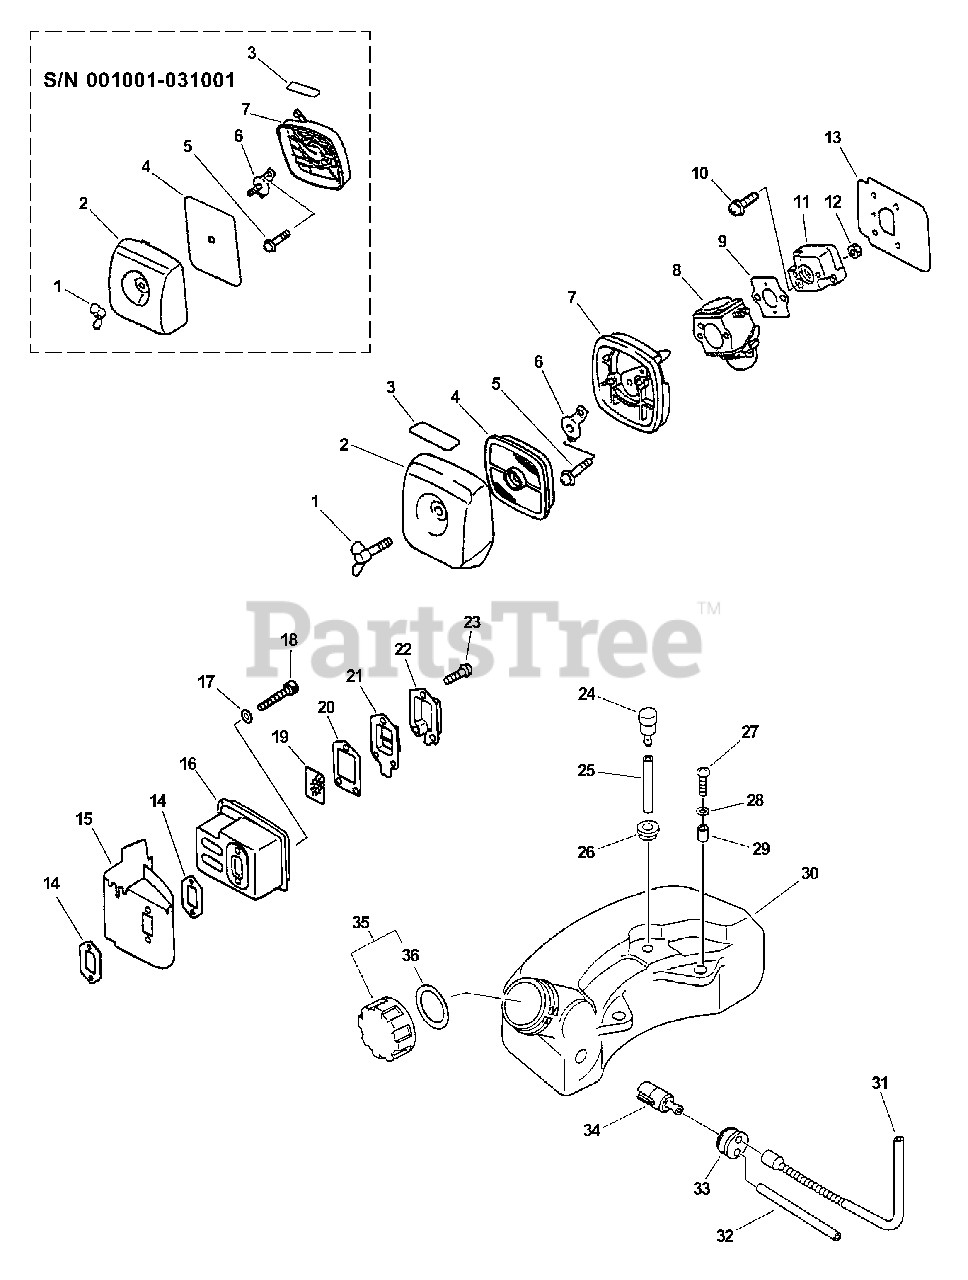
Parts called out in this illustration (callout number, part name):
1	WINGNUT - 6
1	BOLT, WING 5×20
2	COVER, AIR FILTER
3	LABEL, CHOKE
4	FILTER, AIR
4	FILTER, AIR - SINGLE LAYER
5	SCREW 5×65
6	PLATE, PREVENT
7	AIR FILTER CASE ASSY
8	CARBURETOR - C1U-K31A
9	GASKET, INTAKE
10	SCREW 5×20
11	INSULATOR, INTAKE
12	NUT M5
13	HEAT SHIELD, INTAKE
14	GASKET, EXHAUST
15	COVER, EXHAUST
17	WASHER, FLAT 5.5×10×0.8
18	BOLT 5×55
19	SCREEN, SPARK ARRESTER
20	GASKET, EXHAUST
21	GUIDE, EXHAUST
22	GUIDE, EXHAUST - INNER
23	SCREW 4×10
24	VENT ASSY
25	PIPE, FUEL
26	GROMMET
27	SCREW 5×16
28	WASHER 5.5×12×0.8
29	SPACER 6.2×7.8×6
30	TANK, FUEL
31	PIPE, FUEL
32	PIPE, FUEL RETURN 3×6×110
33	GROMMET, FUEL
34	FILTER, FUEL
35	CAP ASSY, FUEL
36	GASKET, FUEL CAP
